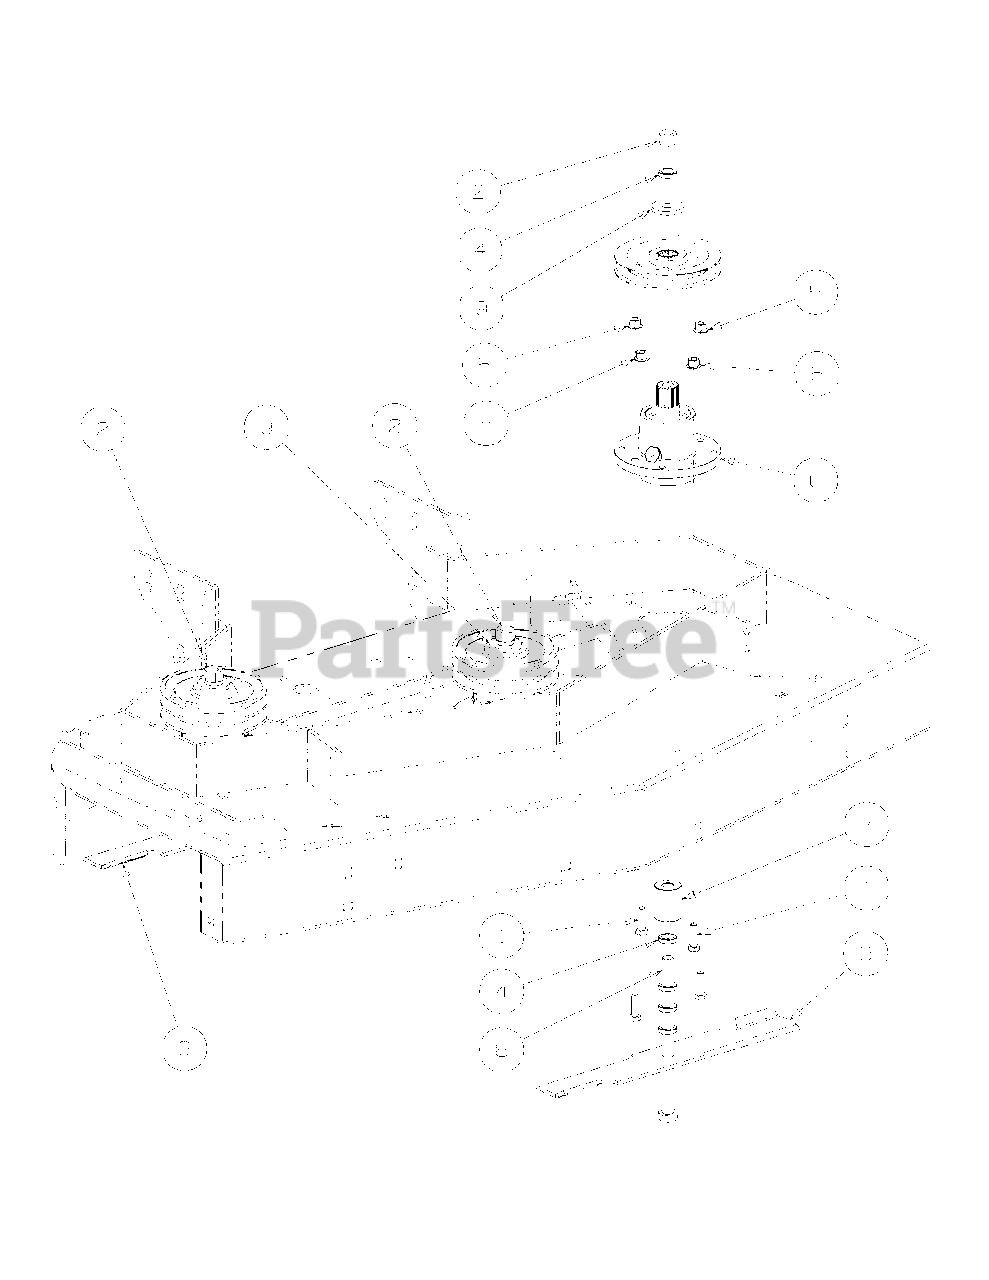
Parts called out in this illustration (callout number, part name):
1	Hex Cap Screw, 3/8-16 x 1-1/4
2	Hex Nut, 5/8-11
3	16 1/2" Rotary Blade
4	Blade Spacer, 5/8 ID, 1/4 Thick
5	Hex Nut Flange Lock, 3/8-16
6	Spindle Assembly
6	Grease Fitting, 1/4-28 x 1.609
7	Blade Spacer, .630 x 1.500 x 1.850
8	Hex Cap Screw, 5/8-11 x 9
9	Flat Washer, .656 ID x 1.313 OD
